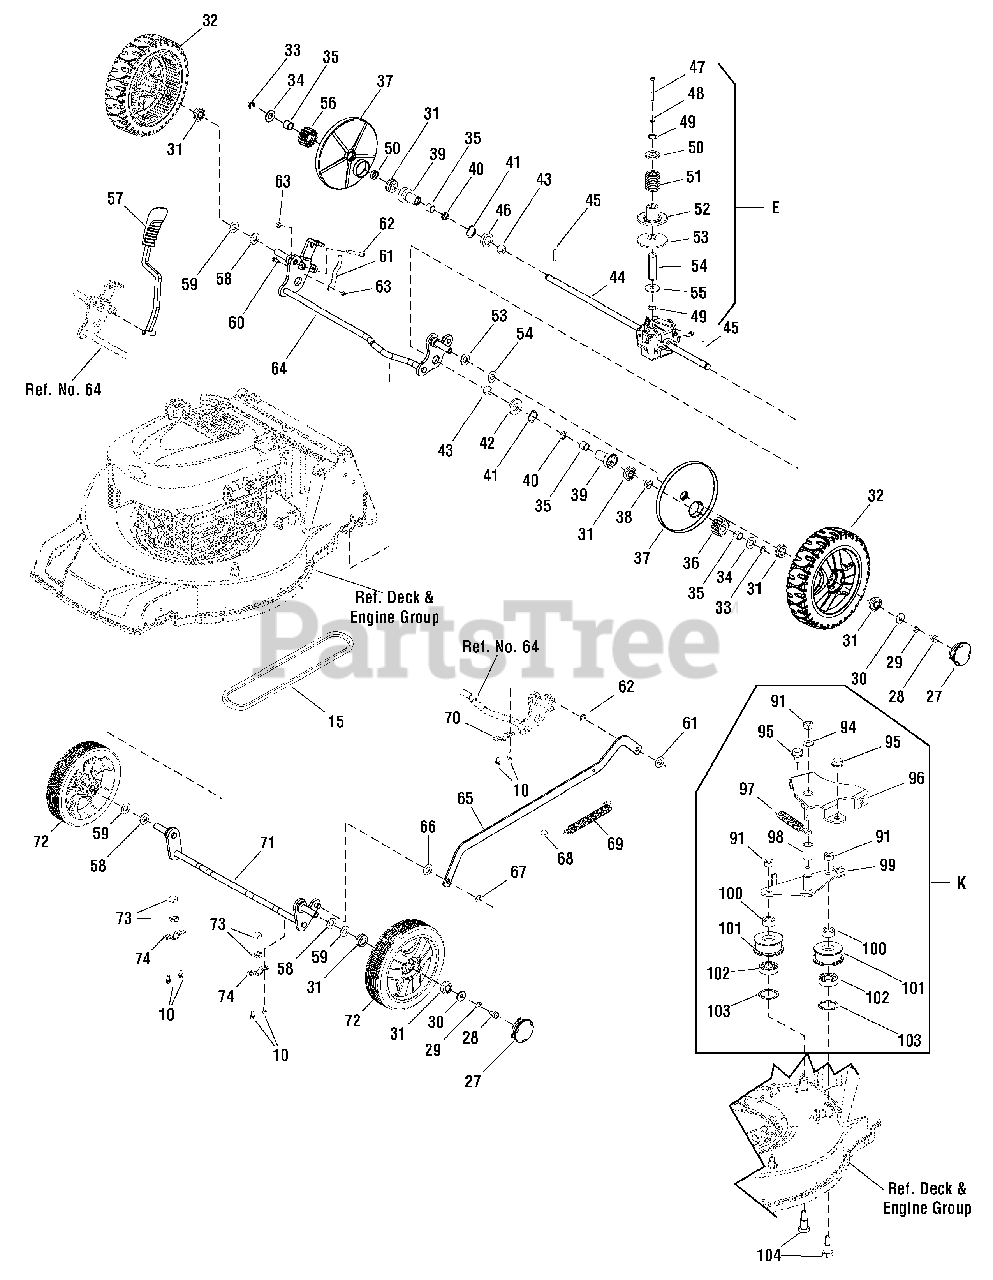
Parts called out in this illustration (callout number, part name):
10	SCREW, Hex Flange, Tapping
15	V BELT, V10 × 845
27	COVER, Wheel
28	BOLT, Hexangular, Full Thread
29	WASHER, Spring
30	WASHER, Flat, C-Class
31	BEARING
32	WHEEL, Rear, 9"
33	RING, Check
34	WASHER, Anti-friction
35	OIL BEARING B
36	PINION, Left
37	SHIELD, Dust, Rear
38	SPACER, Axle
39	BEARING SHEATH
40	RING, Dustproof
41	RING, Elastic, For A-form Axle
42	WASHER, Left Bearing Bracket
43	BALL BEARING, Nylon
44	TRANSMISSION, Variable Speed, 538
45	PIN, Sliding
46	SPACER, Transmission
47	CAPSCREW, Hex Socket Head
48	WASHER, Spring
49	RING, Elastic, For A-form Axle
50	RING, Spring Shield
51	SPRING, Compression
52	Mobile Disc of Pulley
53	DISC, Lower Pulley
54	ADAPTER, Hexagon
55	WASHER, Inner Hexagon
56	PINION, Right
57	LEVER, Height Adjust
58	WASHER, Wheel Axle
59	SPACER, Spring
60	BOLT, Hexangular, Full Thread
61	SPRING, Armature
62	BOLT, Hexangular
63	NUT, Hex, Nylon Insert, Torque Type
64	AXLE, Rear
65	CONNECTING ROD
66	WASHER, Nylon
67	CHECK RING
68	CHECK CAP
69	SPRING, Connecting Rod
70	BRACKET, Upper Ball Bearing
71	AXLE, Front
72	WHEEL, Front, 8"
73	BALL BEARING, Nylon
74	BRACKET, Front Ball Bearing
91	NUT, Hex, Nylon Insert, Torque Type
94	WASHER, Large
95	BOLT, Hex Flange, Tapping
96	PLATE, Tension
97	SPRING, Tension
98	SPACER, Nylon
99	BRACKET, Pulley
100	SPACER, Pulley
101	PULLEY, Tension
102	BALL BEARING, Deep Groove
103	RING, Elastic, For A-form Axle
104	BOLT, Pulley
E	SPEED VARIATOR ASSEMBLY
K	TENSIONAL MECHANISM ASSEMBLY
